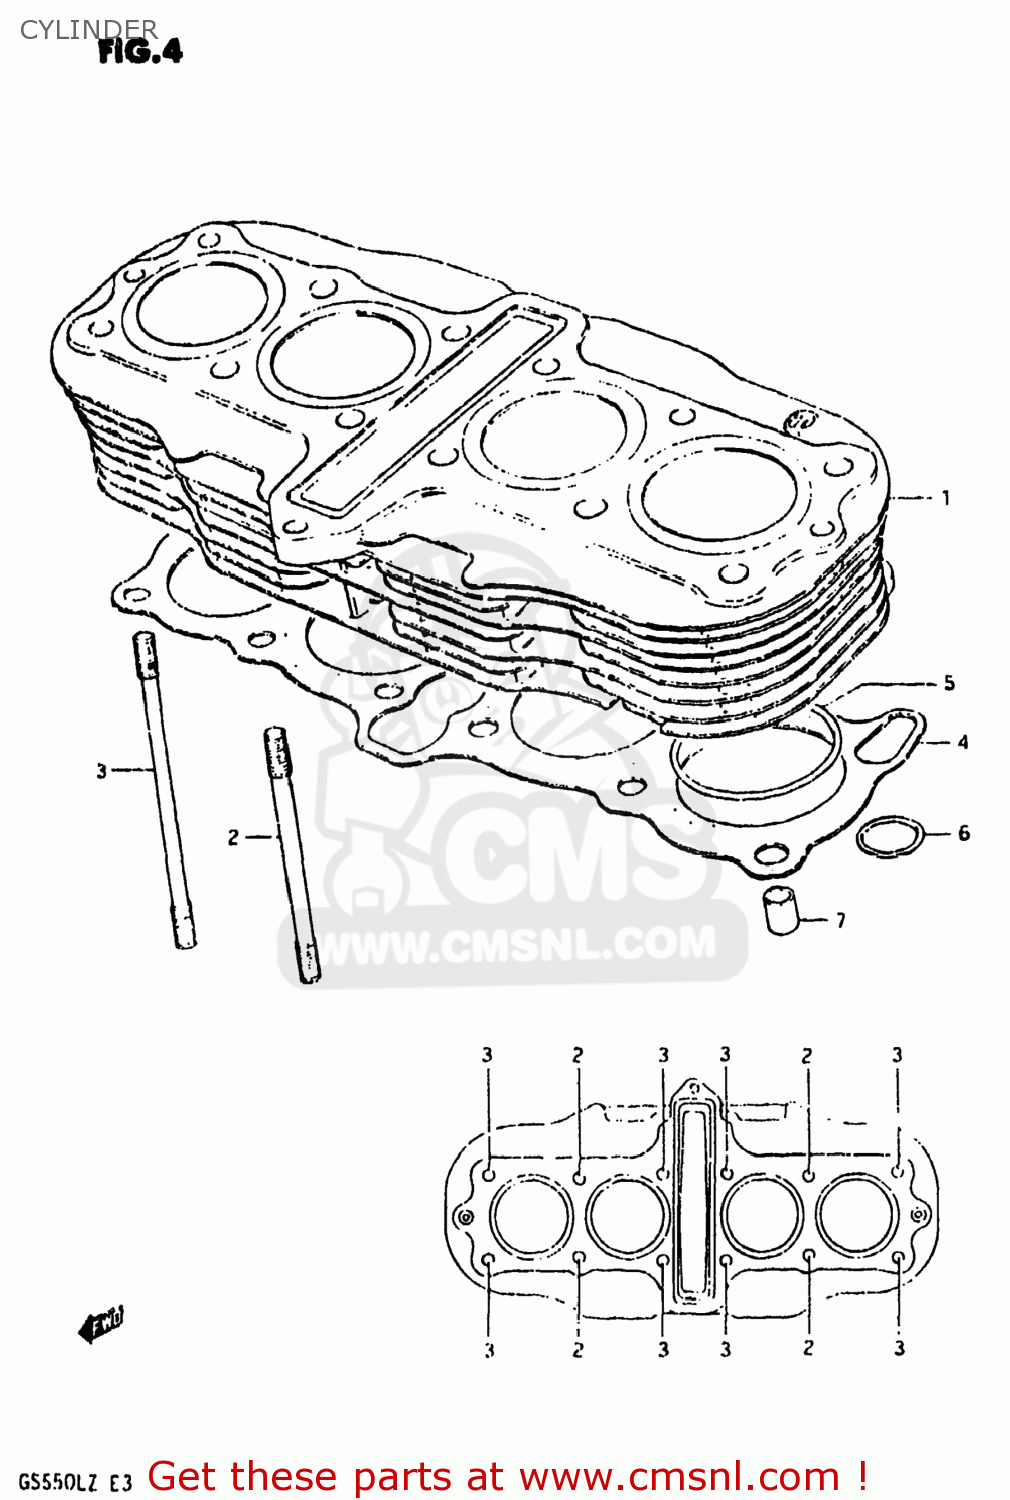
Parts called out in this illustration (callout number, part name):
1	CYLINDER
2	BOLT,STUD
3	BOLT,STUD
4	GASKET,CYLINDER (MCA)
5	O RING(D:2,ID:61)
6	O RING(D:2.4)
7	PIN
